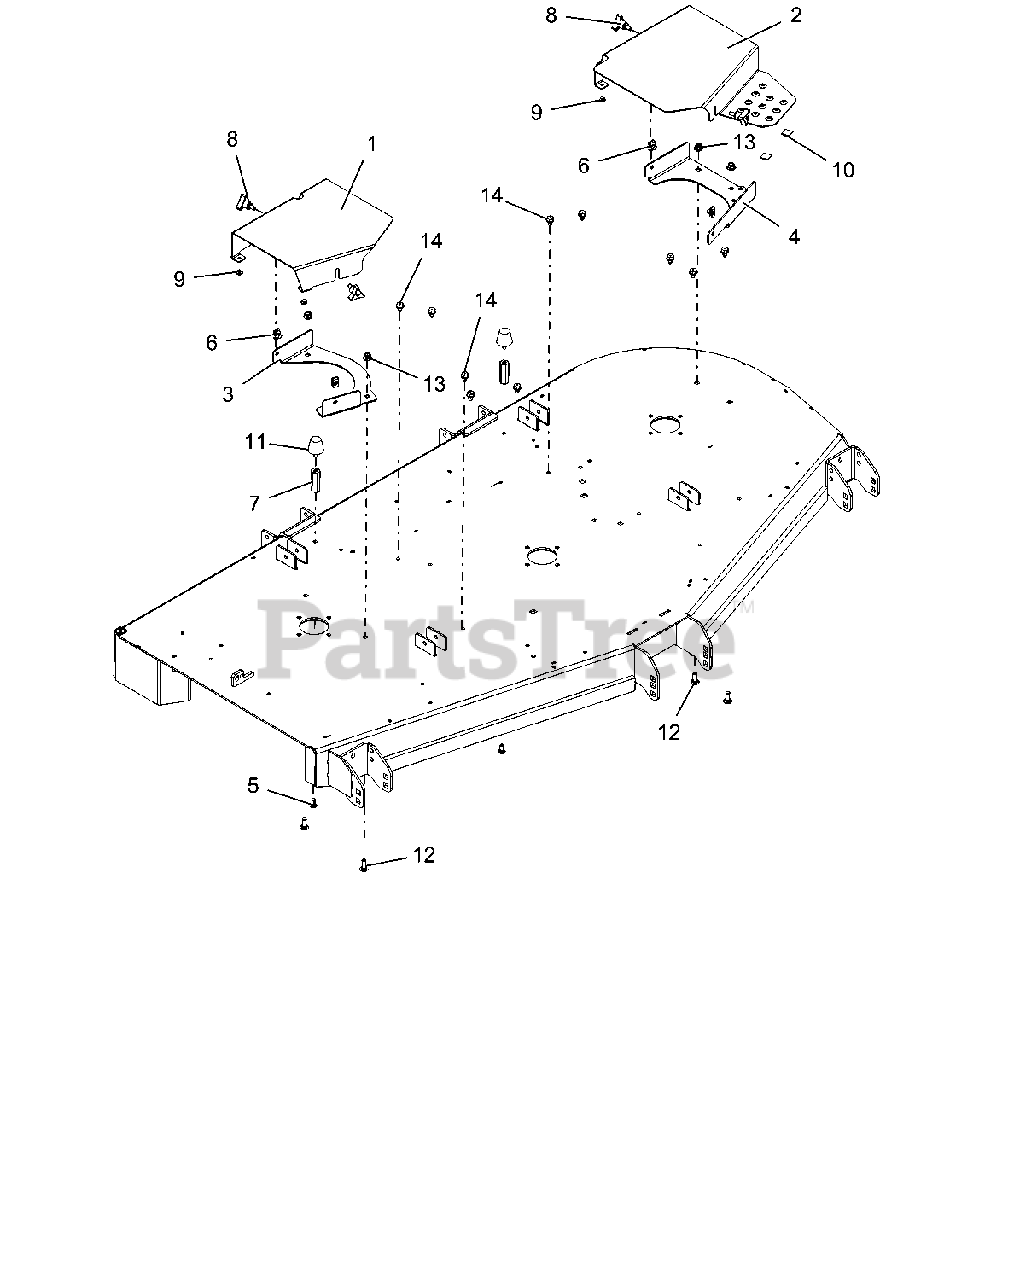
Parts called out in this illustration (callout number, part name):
1	GUARD, RH DECK - RED
2	GUARD, LH BELT - RED
3	BRKT, RH BELT GUARD MTG - RED
4	BRKT, LH BELT GUARD MTG - RED
5	BLT,RDHDSQNK .31-18X.75 LOCTIT
6	NUT-CLIP RETAINER 5/16-18X.56
7	NUT, .31-18X2.25 LG COUPLING
8	KNOB,WING STUD 5/16-18 X .75
9	BUMPER GROMMET
11	BUMPER, RUBBER CONE,STUD MOUNT
12	BLT-RDHDSQNK .38-16X1.00 G5YZ
13	NUT-LK-NYL-FLG .38-16 YWZC
14	SCR-TAP .38-16X.50 HWH TR YWZ
